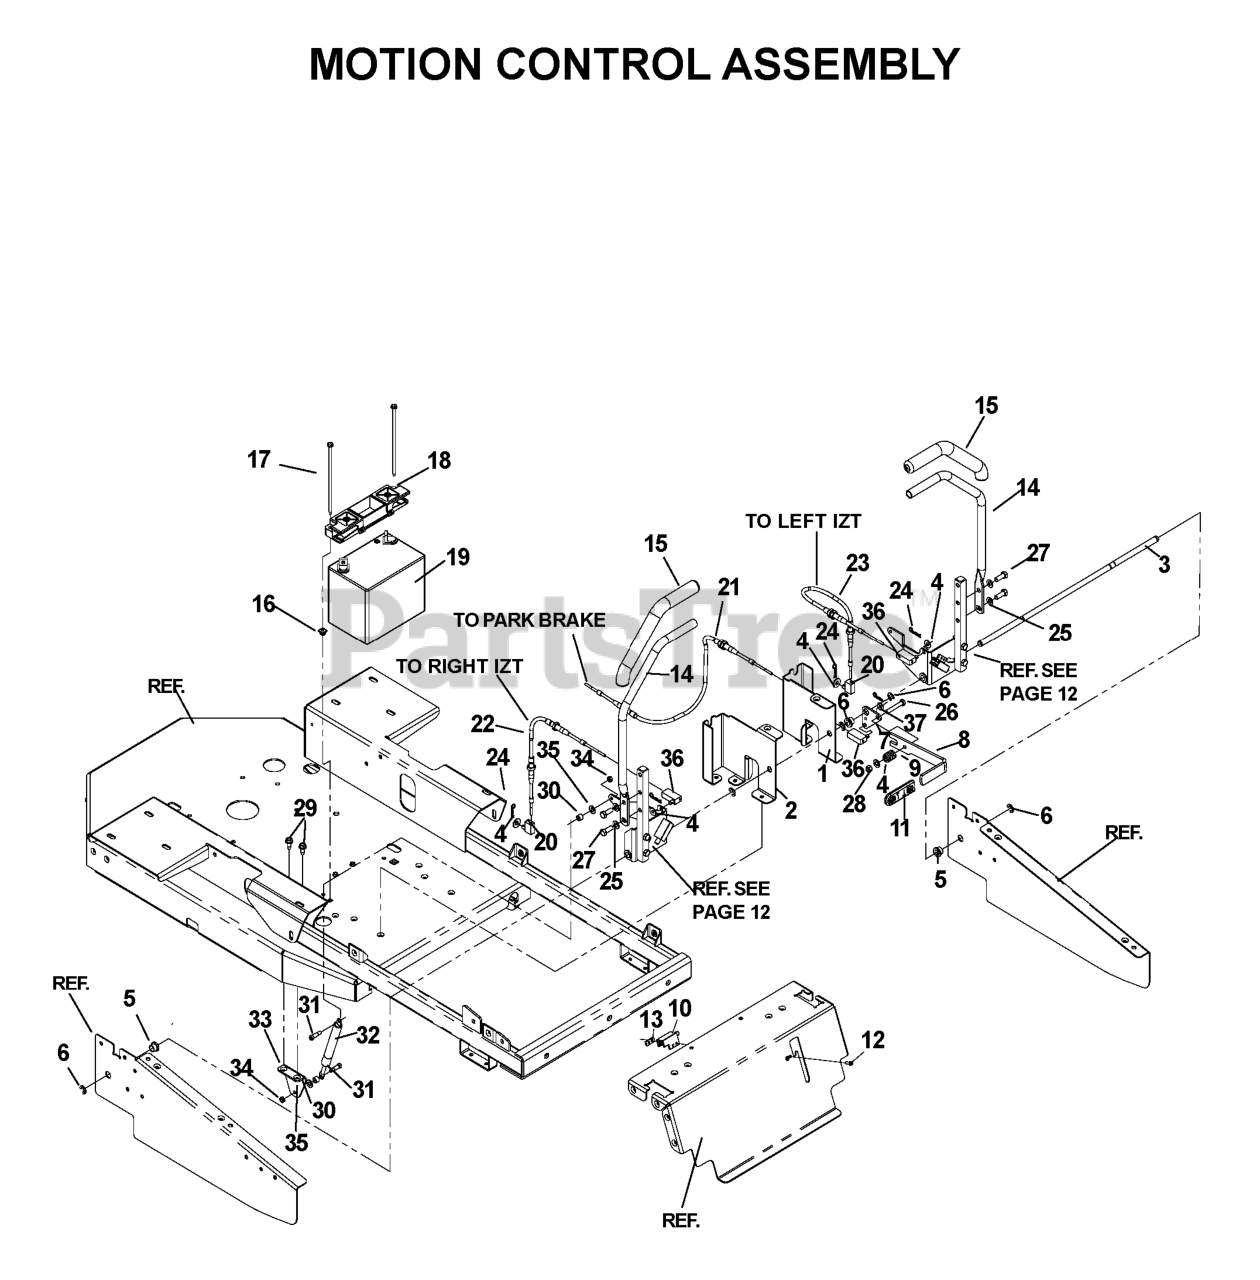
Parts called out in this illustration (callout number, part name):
1	BATTERY SUPPORT-LH
2	BATTERY SUPPORT-RH
3	CONTROL PIVOT SHAFT
4	WASHER 5/16 FLAT
5	BUSHING, FLANGED NYLON
6	E-RING 1/2 (2 2)
7	BRAKE LEVER
8	UPPER BRAKE LEVER
9	COMPRESSION SPRING
10	SWITCH, INTERLOCK
11	GRIP, PARK BRAKE
12	SCREW #10-24 X 5/8
13	TAPPED PLATE
14	CONTROL LEVER-BLACK
16	PUSH NUT-NYLON
17	BOLT - 1/4-20 X 7.5
18	BATTERY HOLD DOWN
19	BATTERY, 12 V 330 AMP
20	LOWER SWIVEL
21	BRAKE CABLE
22	CABLE-RH
23	CABLE-LH
24	HAIRPIN #2
25	WASHER, 3/8 DISC SPRING SPEC
26	HCS 5/16-18X2
27	HCS 3/8-16X1.GRD.5.ZD
28	NUT 5/16 NYLOC
29	BOLT 5/16-18 X 3/4
31	SCREW, 5/16 X 5/8 SHOULDER
33	DAMPENER BRACKET
34	JAM NUT 1/4C (2 2 PW01)
36	UPPER CABLE END
37	FLAT WASHER 5/16 SAE
